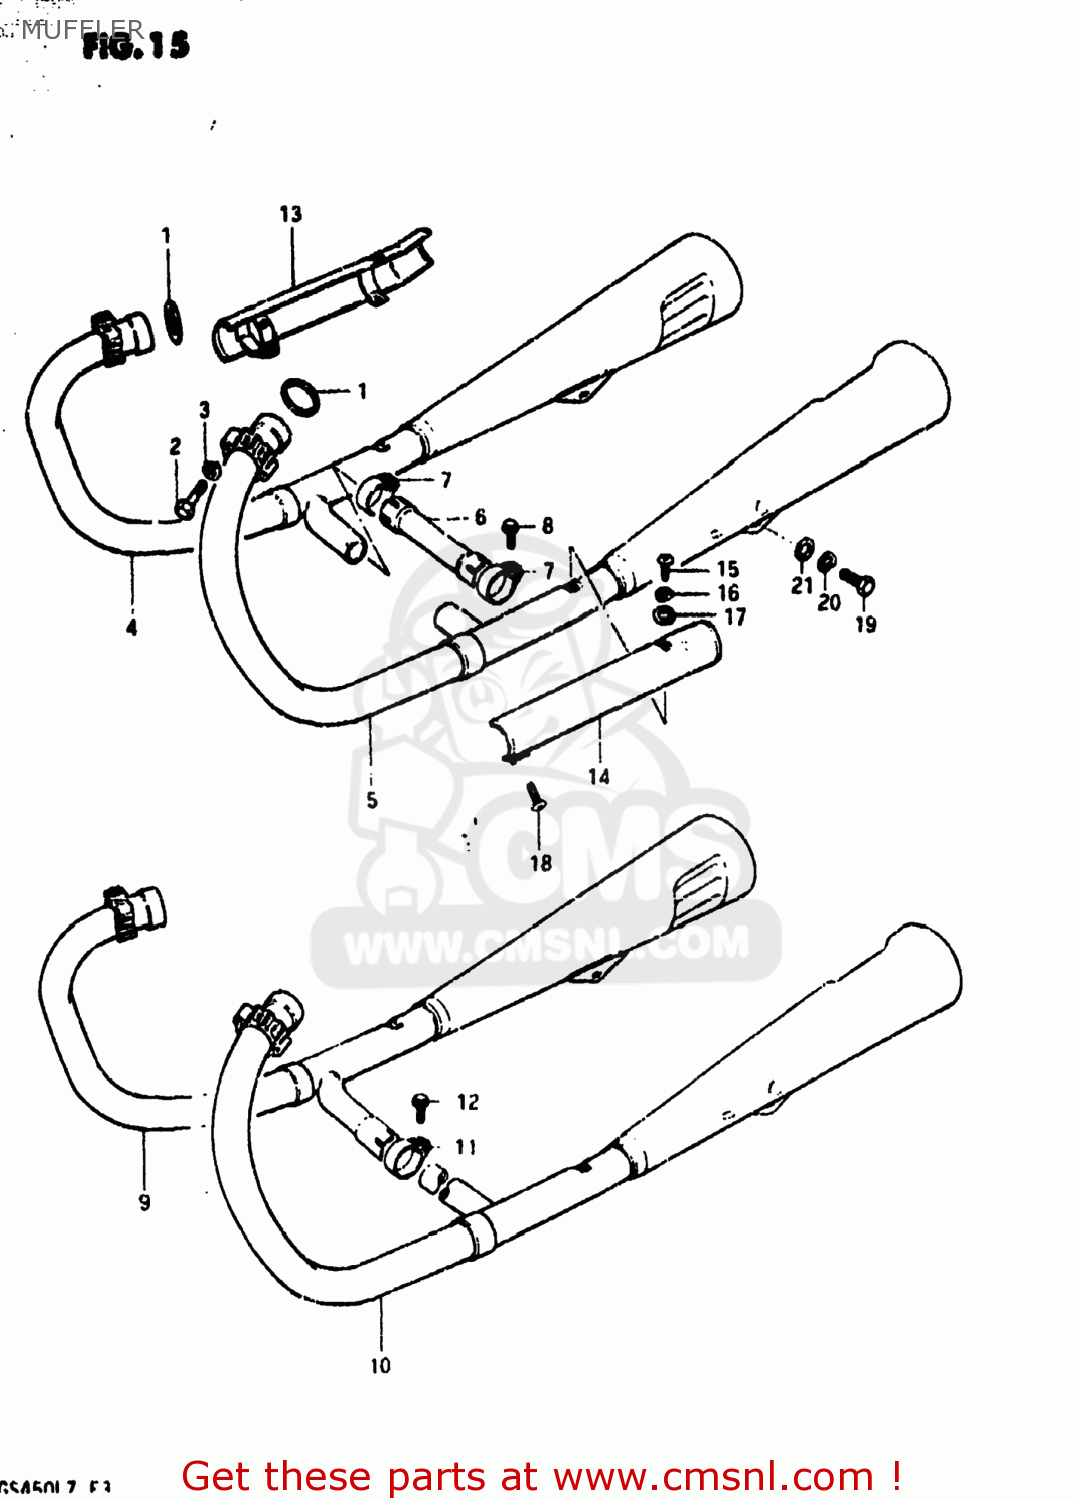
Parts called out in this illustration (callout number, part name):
1	GASKET,EXHAUST PIPE (NAS)
2	BOLT
3	LOCK WASHER
4	BODY,MUFFLER
5	BODY,MUFFLER
6	PIPE,EXHAUST COUPLER
7	CLAMP
8	BOLT
9	BODY,MUFFLER
10	BODY,MUFFLER
11	CLAMP
12	BOLT
13	COVER,MUFFLER
14	COVER,MUFFLER
15	SCREW
16	LOCK WASHER
17	WASHER
18	SCREW
19	BOLT 10X25
20	LOCK WASHER
21	WASHER
